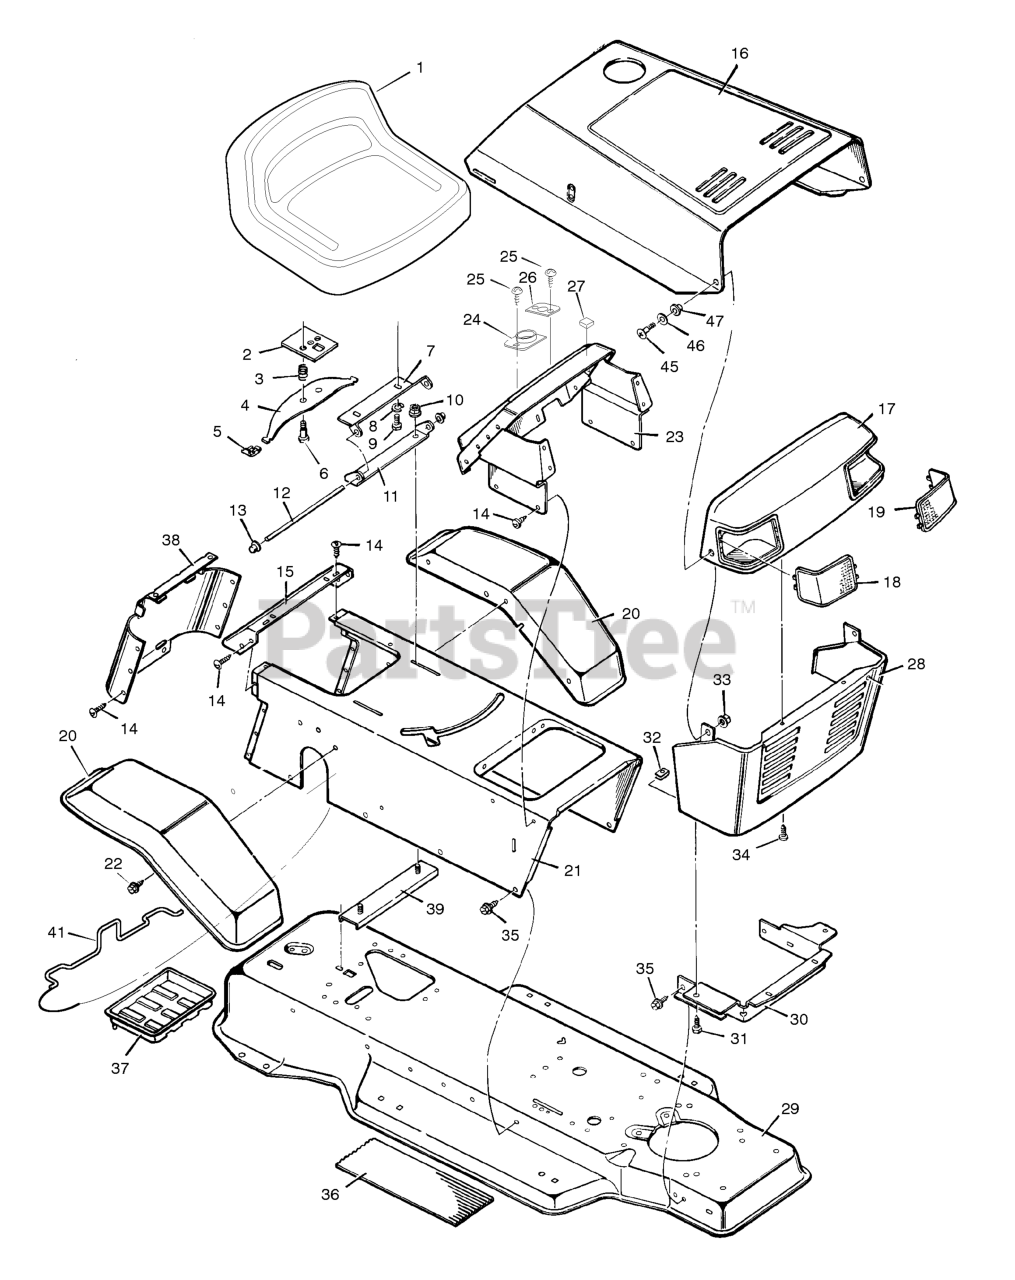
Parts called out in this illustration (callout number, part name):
2	Plate Assembly, Switch
3	Spring, Compression
4	Spring, Seat
5	Glide, Spring
6	Bolt, Shoulder
7	Support, Seat
8	Lockwasher
9	Bolt, Hex
10	Locknut, Flange
11	Bracket, Pivot
12	Rod, Pivot
13	Cap, Push On
14	Screw, Tap
15	Fender, Apron
17	Grille, Upper
18	Lens, Right
19	Lens, Left
21	Console Assembly
23	Dash Panel
24	Bearing, Steering
26	Bearing
27	Bumper
28	Grill, Lower
29	Frame Assembly
30	Support, Grill
33	Locknut, Flange
34	Fastener, Plastic
37	Tray, Battery
38	Cap, Console
39	Channel Assembly
41	Clamp, Battery
45	Bolt, Shoulder
46	Washer, Rubber
47	Eyelet
